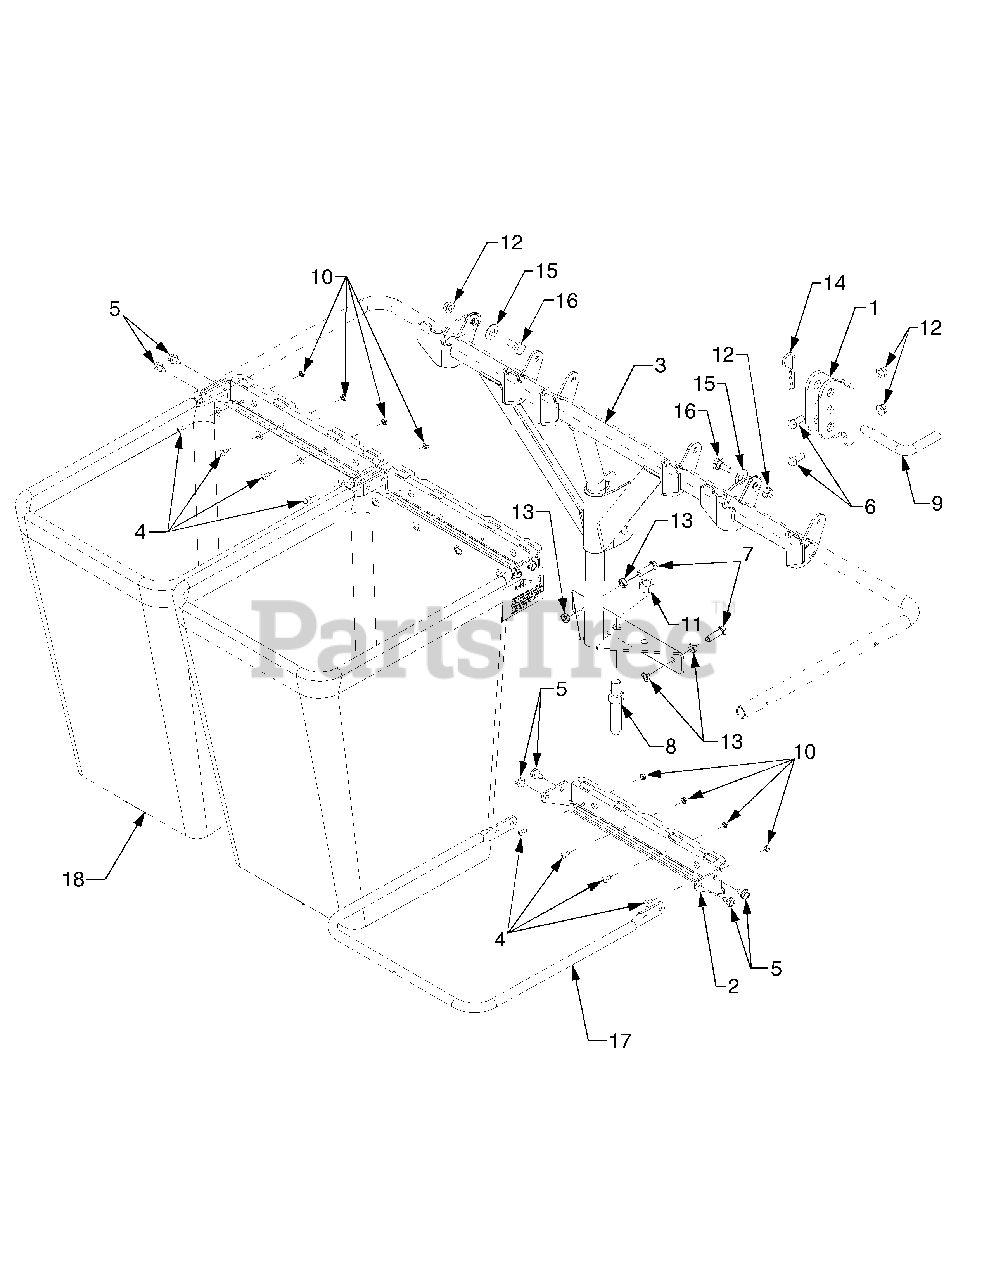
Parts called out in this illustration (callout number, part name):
1	Bracket, Hitch
2	Bracket, Bag Frame Hanger
3	Mounting Tube Assembly
4	Screw, Truss Hd. Mach. 10-24 x .5
5	Screw, Hex Wash. Hd. Tapp 5/16-18 x .625
6	Screw, Hex Cap 3/8-16 x .880 GR5
7	Screw, Hex Cap 3/8-16 x 1.25 GR5
8	Stud, Adapter
9	Pin, Right Angle Clevis
10	Nut, Hex Sems, 10-24
11	Nut, Hex, 5/8-18 GR5
12	Nut, Hex Flange Lock, 3/8-16
13	Nut, Hex Jam, 3/8-16 GR5
14	Pin, Internal Cotter
15	Washer, Belleville, .51 x 1.14 x .04
16	Screw, Shoulder .50 x .27: 3/8-16
17	Tube, Grass Bag Frame
18	Bag, Grass Catcher
